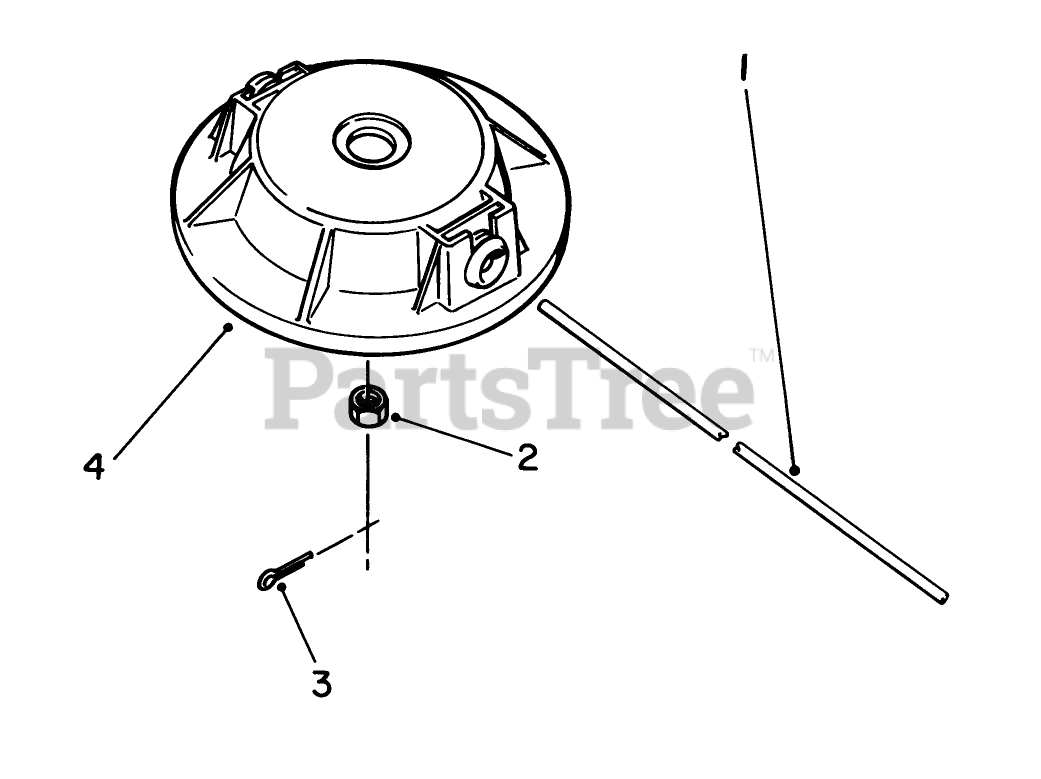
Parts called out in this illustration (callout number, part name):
1	LINE PACK (100)
3	PIN-COTTER
4	CUTTER HEAD-PLASTIC
